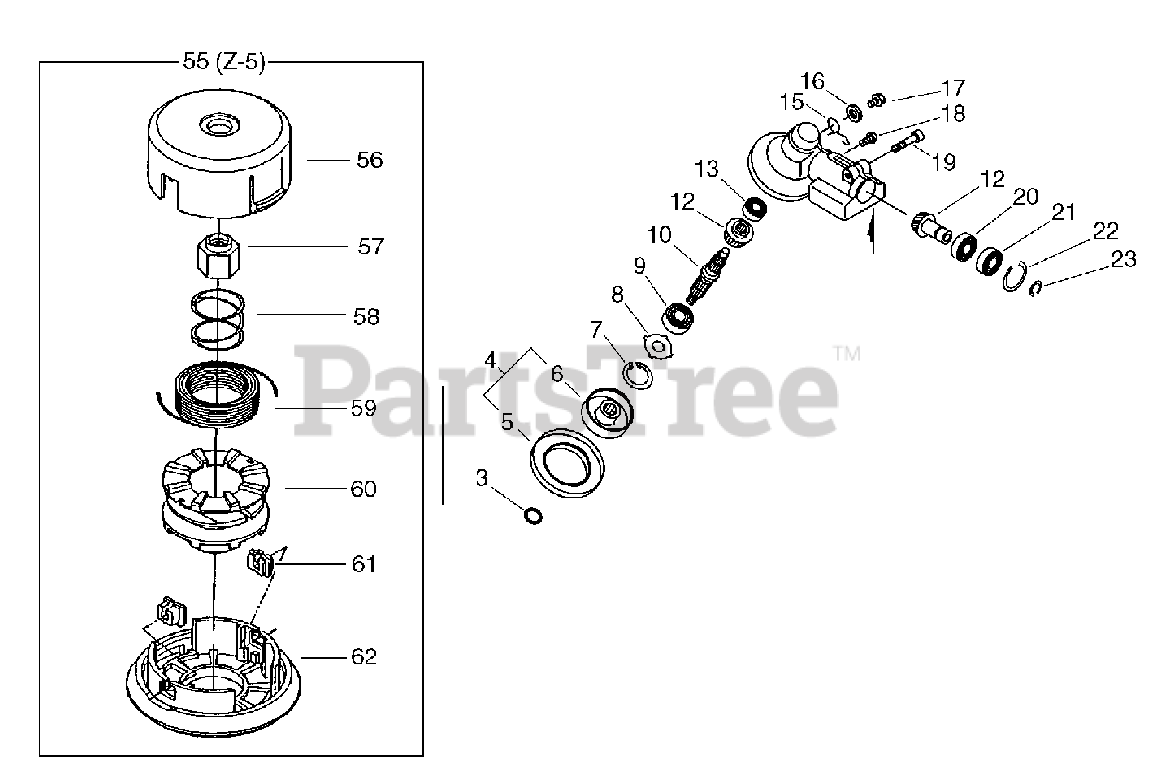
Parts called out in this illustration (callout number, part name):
3	O-RING - 12
4	ADAPTOR, BLADE - UPPER
4	BLADE ADAPTER KIT
5	PLATE, CUP
6	ADAPTOR, BLADE - UPPER
7	RING, RETAINING - 32
9	BEARING, BALL - 6201
10	GEAR - SHAFT
12	GEAR SET
13	BEARING, BALL - 629
15	SPRING
16	WASHER - 8
17	BOLT - 8X6
17	BOLT - 8X8
18	SCREW - 5X10
19	SCREW - 6X30
20	BEARING, BALL - 6001
21	BEARING, BALL - 6001
22	RING, RETAINING - 28
23	RING, RETAINING - 12
40	LABEL - CAUTION
40	TRIMMER HEAD ASSY
41	REEL, ROPE
41	WASHER - 24
42	SPOOL
42	EYELET
43	EYELET
43	SPOOL
43	HOUSING
44	LINE, TRIMMER
44	NUT
45	SPRING
46	SPRING
46	TAP KNOB
47	COVER, DRUM
47	SPOOL
48	NUT
48	LINE, TRIMMER
49	NUT
49	COVER
50	SCREW - 6X10
55	TRIMMER HEAD ASSY
56	HOUSING
59	LINE, TRIMMER
